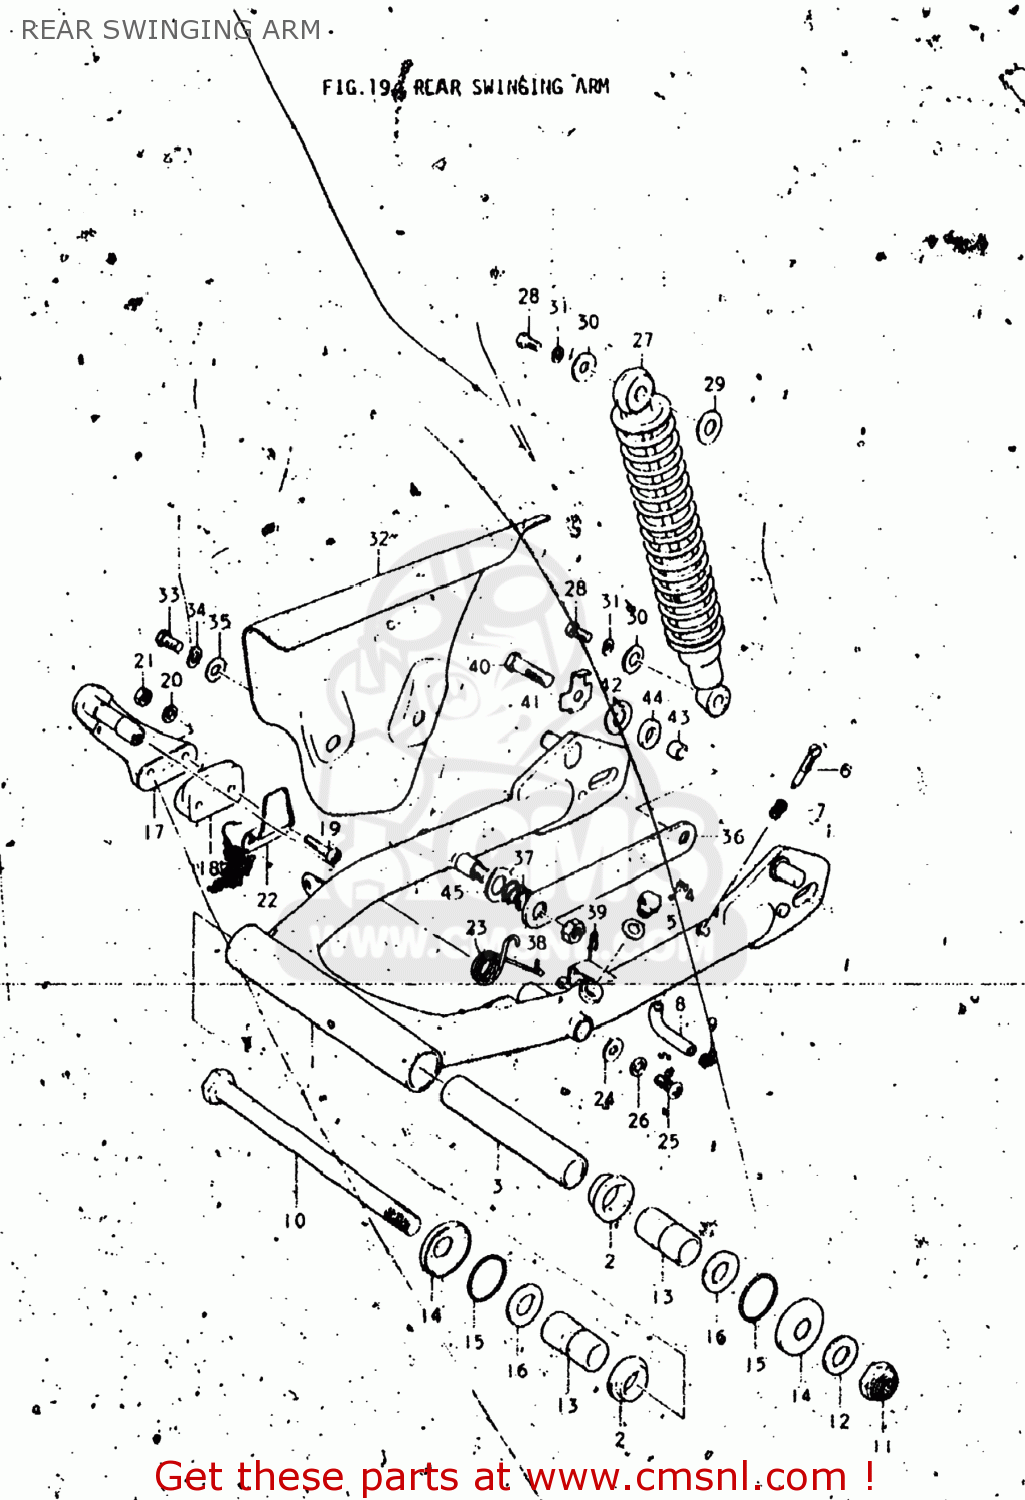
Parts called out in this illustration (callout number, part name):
1	SWING ARM ASSEMBLY,REAR
2	BUSHING
3	SPACER,SWING ARM,CENTER
4	PLUG
5	GASKET(14.5X20.5X1) (NAS)
6	BUFFER,CHAIN TOUCH DEFLECTOR
7	SPRING
8	HOSE
9	CLIP
10	SHAFT,REAR SWING ARM
11	NUT
12	WASHER
13	SPACER,REAR SWING ARM
14	COVER
15	O RING(D:3,ID:29.5)
16	WASHER(14.5X29X2.3)
18	RUBBER,CHAIN TENSIONER
19	SCREW(5X27)
20	LOCK WASHER
21	NUT
23	SPRING
24	WASHER(6.5X16X1.2)
25	SCREW 6X12
26	LOCK WASHER
27	ABSORBER ASSEMBLY,REAR SHOCK
28	BOLT
29	WASHER
30	WASHER (6.5X24X1.6)
31	LOCK WASHER
32	CASE,CHAIN
33	BOLT
34	LOCK WASHER
35	WASHER
36	TORQUE LINK,REAR
37	SPRING
38	NUT
39	CLIP
40	BOLT
41	WASHER
42	WASHER
43	SPACER
44	WASHER (14X25X3)
45	WASHER
